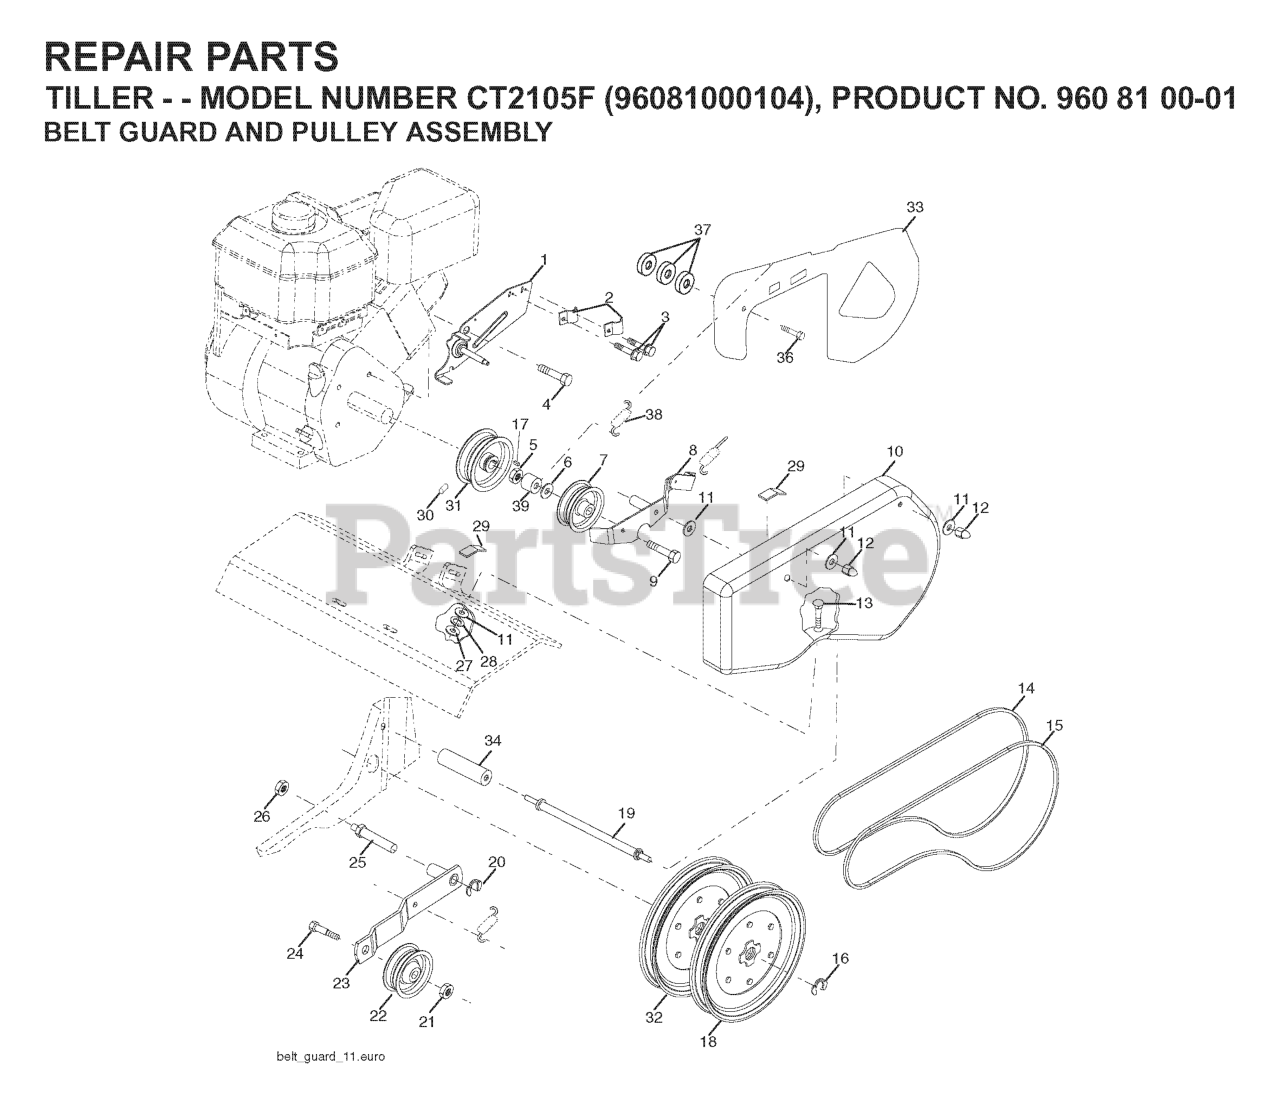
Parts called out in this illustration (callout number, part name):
1	RP BRKT.ASM.GUARD.BELT
2	CONDUIT CLIP T
3	TAPPING SCREW
5	LOCKNUT
7	PULLEY
8	ARM
9	BOLT
11	WASHER
12	CAP
15	BELT
16	RETAINING RING LT
18	SHEAVE,TRANS."D"
19	BOLT.BELT.GUARD
20	KLIP RING TI
21	NUT
22	PULLEY, IDLER
23	ARM, IDLER
25	SHAFT.IDLER.TILLER
26	JAM NUT TI
27	NUT
28	LOCKWASHER
29	PAD IDLER TI
32	SHEAVE.TRANS
37	WASHER
38	SPRING.EXTENSION
